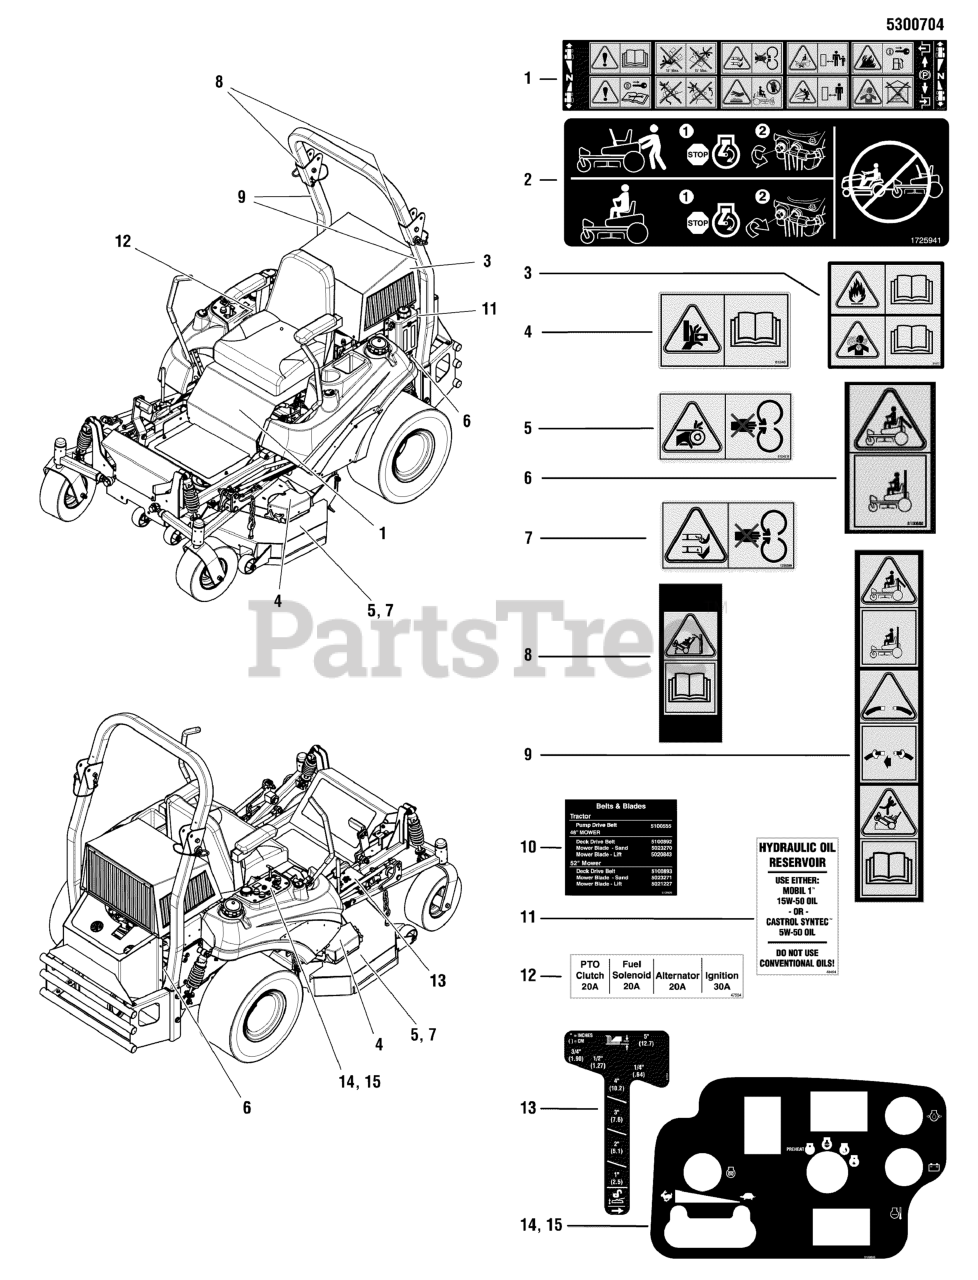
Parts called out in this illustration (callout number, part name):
1	DECAL, MAIN, CE
2	DECAL, CZT HYDRO RELEASE
3	DECAL, DANGER, CE
4	DECAL, PINCH POINT, CE
5	DECAL, CE DANGER
6	DECAL, SAFETY, CE ROPS, OBS
7	DECAL-DANGER ROTATING BLADE SYMBOLS
8	DECAL, WARNING, ROLL BAR, CE
9	DECAL, SAFETY, CE ROPS
10	DECAL, BELTS & BLADES, YANMAR
11	DECAL, OIL RESEVOIR
12	DECAL, FUSE LOCATION
13	DECAL-HEIGHT CITATION
14	DECAL, CONTROL PANEL - IS2000 YANMAR
15	DECAL, CONTROL PANEL - IS2000 YANMAR
